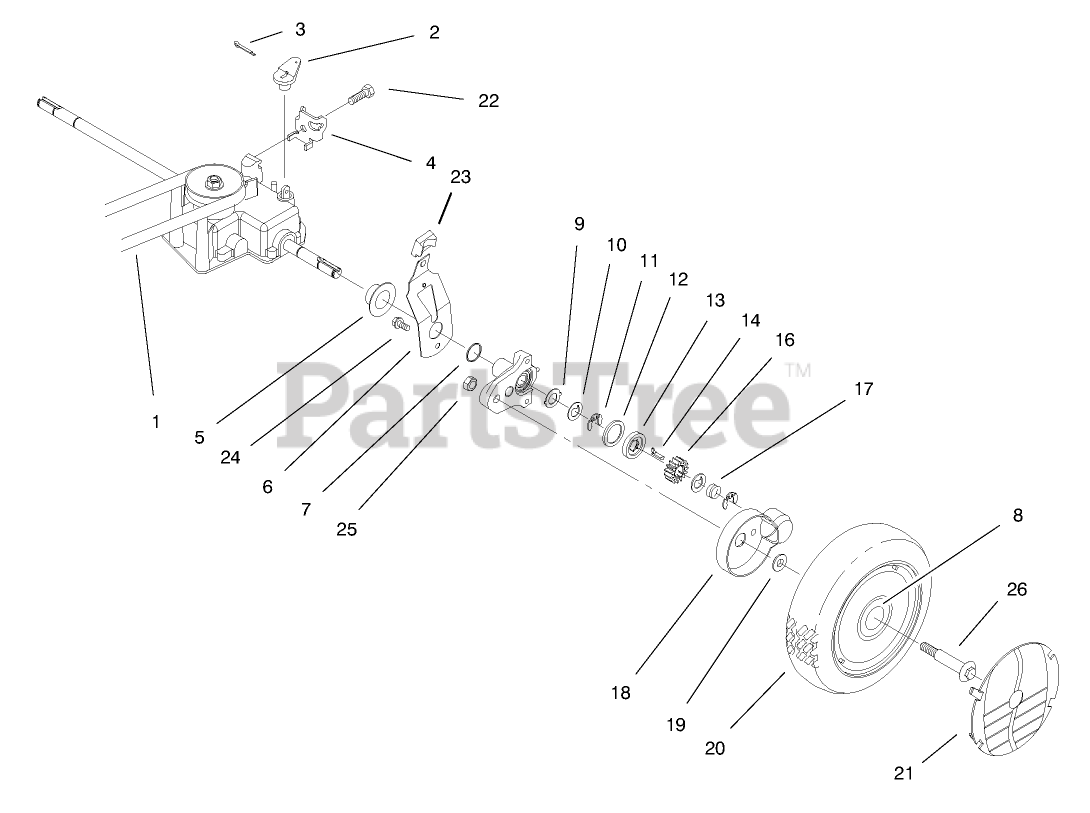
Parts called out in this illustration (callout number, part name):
1	V-BELT
2	LEVER-SHIFT
3	PIN-COTTER
4	CLAMP-CABLE
5	CAP-END
6	SPRING ARM ASM
7	O-RING
8	BUSHING
9	WASHER-ARM, PIVOT
10	WASHER-THRUST, KEYED
11	RING-RETAINING,CLIP
12	RING-FRICTION
13	WASHER-CLUTCH
14	KEY-ROCKING, LH
16	GEAR-PINION
17	SPRING-COMPRESSION
18	COVER-WHEEL
19	SPACER-COVER, WHEEL
20	WHEEL AND TIRE ASM
22	SCREW-HWHTF
23	KNOB-ARM
24	SCREW-HWH
25	NUT-LOCK
